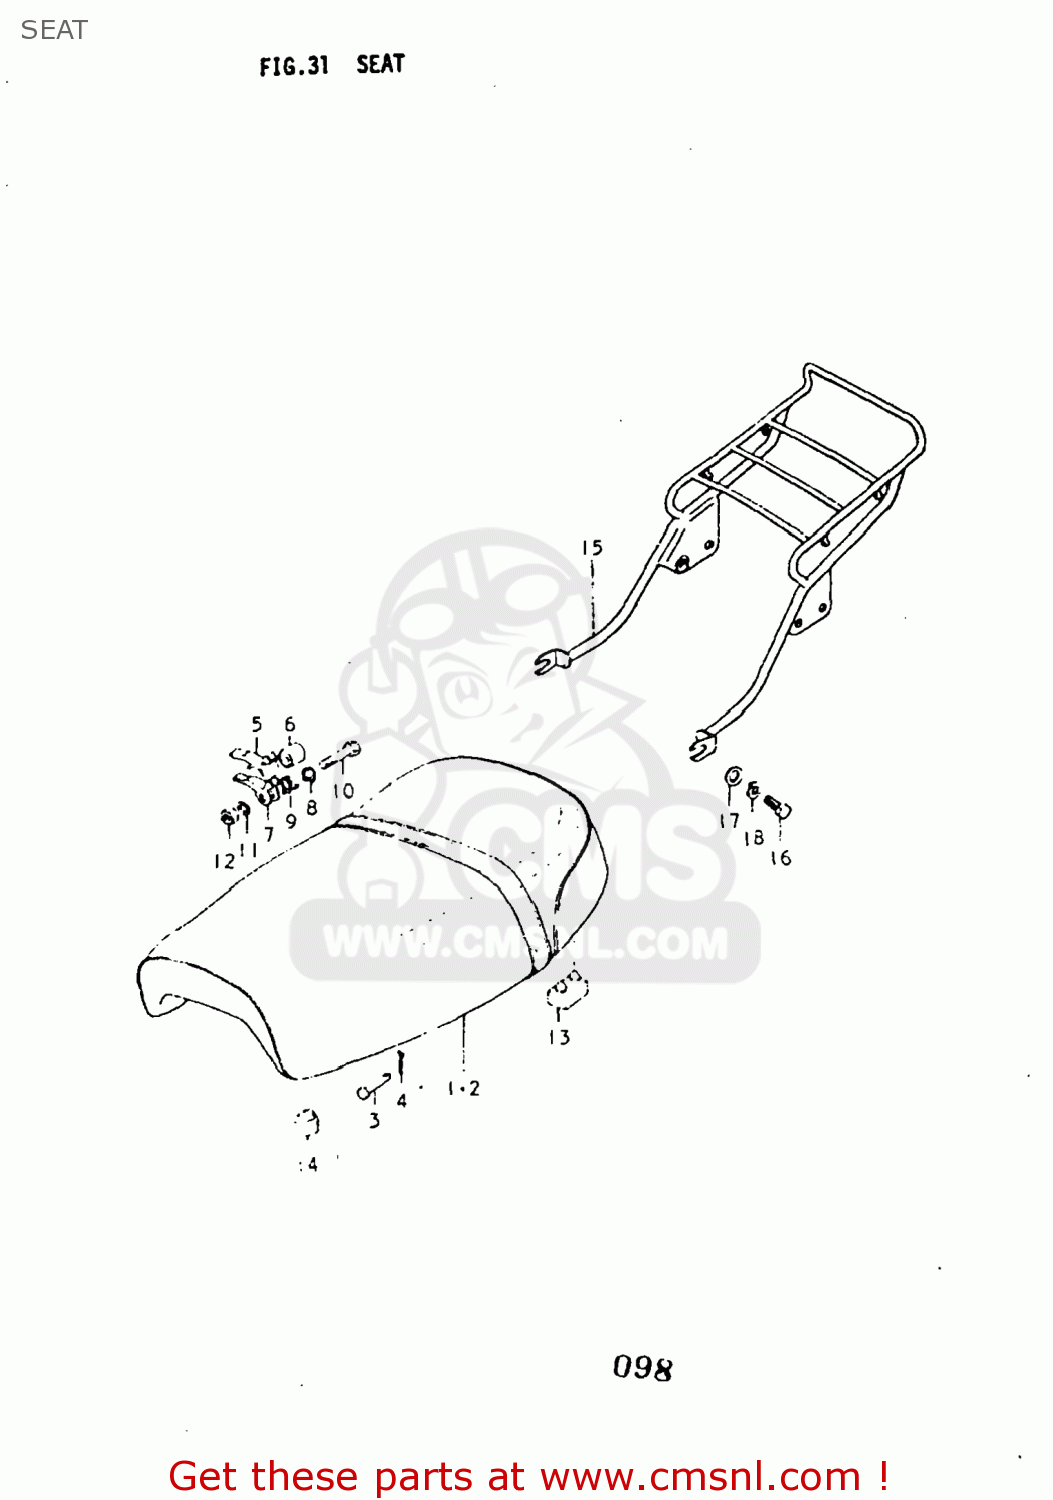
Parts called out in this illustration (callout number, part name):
1	SEAT ASSEMBLY
2	SEAT ASSEMBLY
3	PIN
4	PIN
5	STRIKER,SEAT LOCK
6	BUSHING
7	STRIKER,SEAT LOCK
8	STRIKER,SEAT LOCK
9	SPRING
10	BOLT 8X45
11	LOCK WASHER
12	NUT
13	CUSHION
14	CUSHION(11.5X22X20)
15	CARRIER
16	BOLT
17	WASHER
18	LOCK WASHER
